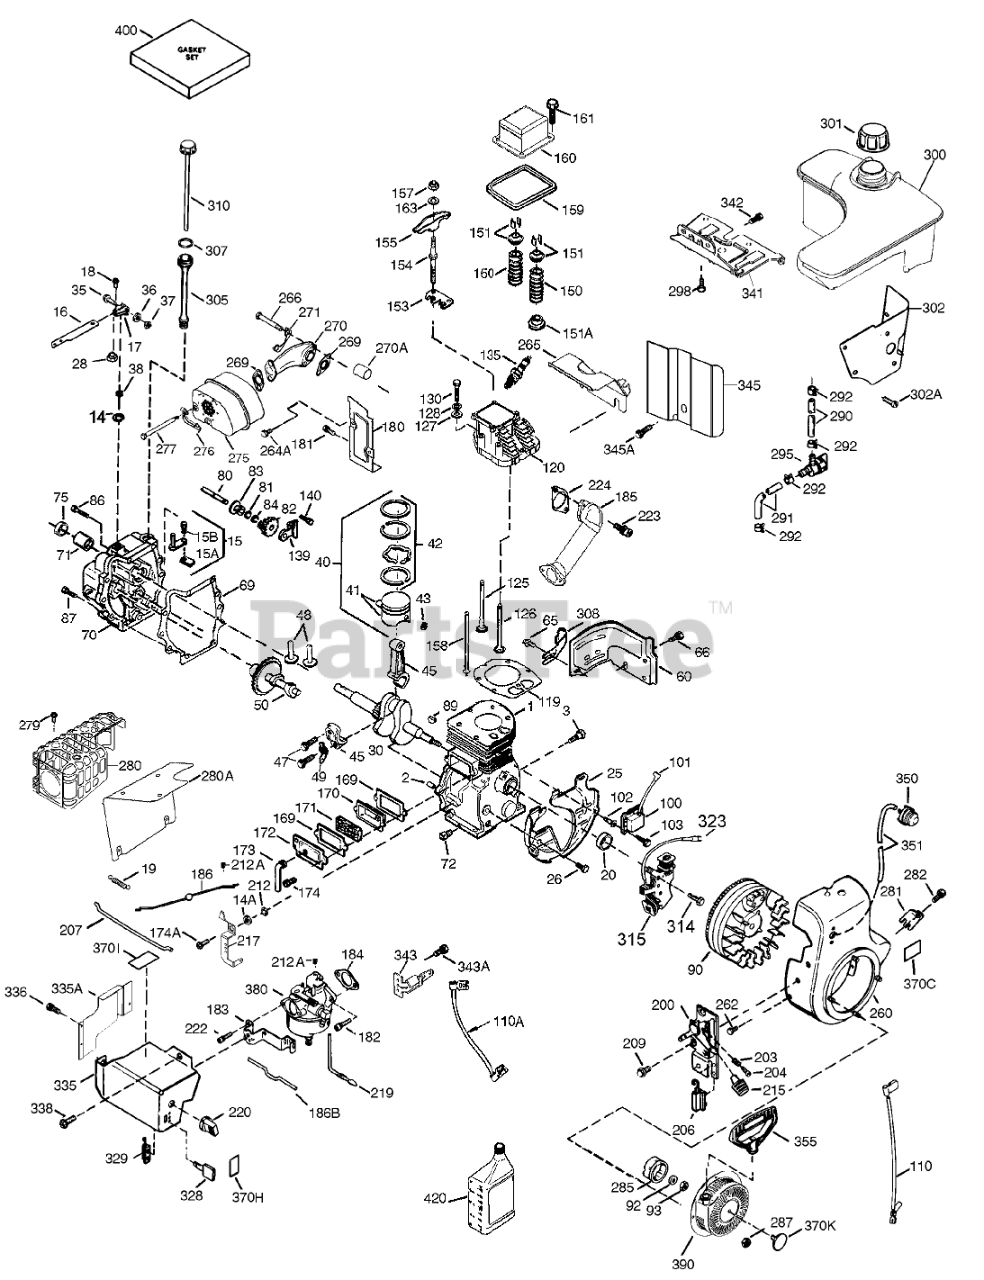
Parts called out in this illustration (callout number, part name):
1	Cylinder (Incl. Ref.# 2, 20 & 72)
2	Pin-Dowel
3	Screw (1/4-20x1/2)
14	Washer-Flat
14A	Washer
15	Governor Rod Ass-y (Incl. Ref.#15A & 15B)
15A	Yoke-Governor
15B	Screw (6-40x5/16)
16	Lever-Governor
17	Clamp-Lever, Governor
18	Screw (T-15, 8-32x7/16)
19A	Spring-Extension
20	Seal-Oil
25	Baffle-Housing, Blower
26	Screw (1/4-20x19/32)
28	Nut-Lock
30	Crankshaft
35	Screw
36	Washer-Lock
37	Nut-Lock
38	Ring-Retaining
40	Piston-Pin and Ring Set (STD)
40	Piston- Pin and Ring Set (.010 O S)
41	Piston & Pin Ass-y (Std.)(Incl. Ref.#43)
41	Piston & Pin Ass-y (.010)(Incl. Ref.#43)
42	Ring Set (STD)
42	Ring Set (.010 O S)
43	Ring-Retaining, Piston Pin
45	Connecting Rod ASM (Incl. Ref.# 47 & 49)
47	Bolt-Rod, Connecting
48	Lifter-Valve
49	Dipper-Oil
50	Camshaft (MCR)
60	Extension-Housing, Blower
65	Screw (10-24 x 9/16)
66	Screw
69	Gasket-Cover, Cylinder
70	Cylinder Cover (Incl. Ref.#14,15,38,71,75)
71	Bushing-Crankshaft
72	Plug-Drain, Oil (SQH 1/4-18)
75	Seal-Oil
80	Shaft-Governor
81	Washer-Flat
82	Governor Gear ASM
83	Spool-Governor
84	Ring-Retaining
86	Screw (1/4-20x1-3/16)
87	Screw (1/4-20x1-11/16)
89	Key-Flywheel
90	Flywheel ASM
92	Washer-Belleville
93	Nut-Flywheel
100	Ignition-Solid State
101	Cover-Spark Plug
102	Stud-Mounting, Solid State
103	Screw (T-15, 10-24 x 15/16)
110	Wire-Ground
110A	Wire-Ground
119	Gasket-Head, Cylinder
120	Cylinder Head (incl. Ref. #151A)
125	Valve-Exhaust (STD)
125	Valve-Exhaust (1/32)
126	Valve-Intake (STD)
127	Washer-Flat
128	Washer-Belleville
130	Screw (5/16-18 X 2-1/2)
135	Spark Plug-Resistor (R N 4C)
139	Bracket-Gear, Governor
140	Screw (10-24x1/2)
150	Spring-Valve
151	Keeper-Spring, Valve
151A	Cap-Spring, Valve
153	Guide-Rod, Push
154	Stud-Arm, Rocker
155	Arm-Rocker
157	Nut-Jam
158	Rod-Push
159	Gasket-Cover, Rocker Arm
160	Cover-Arm, Rocker
161	Screw
163	Washer
169	Gasket-Cover, Valve
170	Body-Breather
171	Element-Breather
172	Cover-Valve
173	Tube-Breather
174	Screw
174A	Screw (10-24 X 29/32)
180	Extension-Housing, Blower
181	Screw (10-24 x 9/16)
182	Screw (T-30, 1/4-20 X 27-32)
183	Bracket-Choke
184	Gasket-Carburetor To Intake Pipe
185	Pipe-Intake
186	Link-Governor
186B	Spring-Choke
200	Control Bracket (Incl. Ref.#203, 204 & 206)
203	Spring-Compression
204	Screw (T-10, 5-40x7/16)
206	Terminal
207	Link-Throttle
209	Screw (10-32 x 1/2)
212	Bushing
212A	Bushing
215	Knob-Control
216	Lever-Bellcrank
219	Rod-Choke
220	Knob-Control
222	Screw (10-32 x 1/2)
223	Screw (T-30, 5/16-18 X 7/8)
224	Gasket-Pipe
260	Housing-Blower
262	Screw
264A	Screw (1/4-20 X 5/8)
265	Cover-Head, Cylinder
266	Screw (5/16-18 X 1-9/32)
269	Gasket-Manifold, Exhaust
270	Manifold, Exhaust
270A	Liner-Port, Exhaust
271	Plate-Locking
275	Muffler
276	Locking Plate
277	Screw (5/16-18 X 4-1/2)
279	Screw (10-32 x 1/2)
280	Shield-Heat
280A	Shield-Heat, Radiation
281	Screw
282	Screw (8-32 x 3/8)
285	Cup-Starter
287	Nut and Lock Washer (1/4-28)
290	Line-Fuel
291	Line-Fuel (8.62)
292	Clamp-Line, Fuel
295	Valve-Shut Off, Fuel
298	Screw (1/4-15x7/8)
300	Fuel Tank (Incl. Ref.# 292 & 301)
301	Cap-Fuel
302	Extension-Tank, Fuel
302A	Screw (10-32 x 1/2)
305	Tube-Fill, Oil
307	O-Ring
308	Clip-Tube, Fill
310	Dipstick
314	Screw (1/4-20 x 3/4)
315	Alternator Coil (18 Watt)(Incl. Ref.# 323)
323	Terminal
328	Key-Ignition
329	Terminal
335	Spring
335A	Cover-Carburetor
336	Screw (10-32 x 1/2)
338	Screw (10-32 x 1/2)
341	Bracket-Tank, Fuel
342	Screw (5/16-18 X 7/8)
343	Bracket-Switch, Key
343A	Screw (8-32 x 23/64)
345	Baffle-Heat
345A	Screw (10-32 x 1/2)
350	Primer ASM
351	Line-Primer
355	Handle-Starter, Mitten Grip
370C	Decal-Primer, International Symbol
370H	Decal-Choke
370I	Decal-Warning (Bilingual)
370J	Decal-Choke
370K	Decal-Tecumseh Logo for Top of Recoil Starter
380	Carburetor (Incl. Ref.# 184)
390	Starter-Rewind
400	Gasket Set
420	Oil-Engine, S A E 5W30
